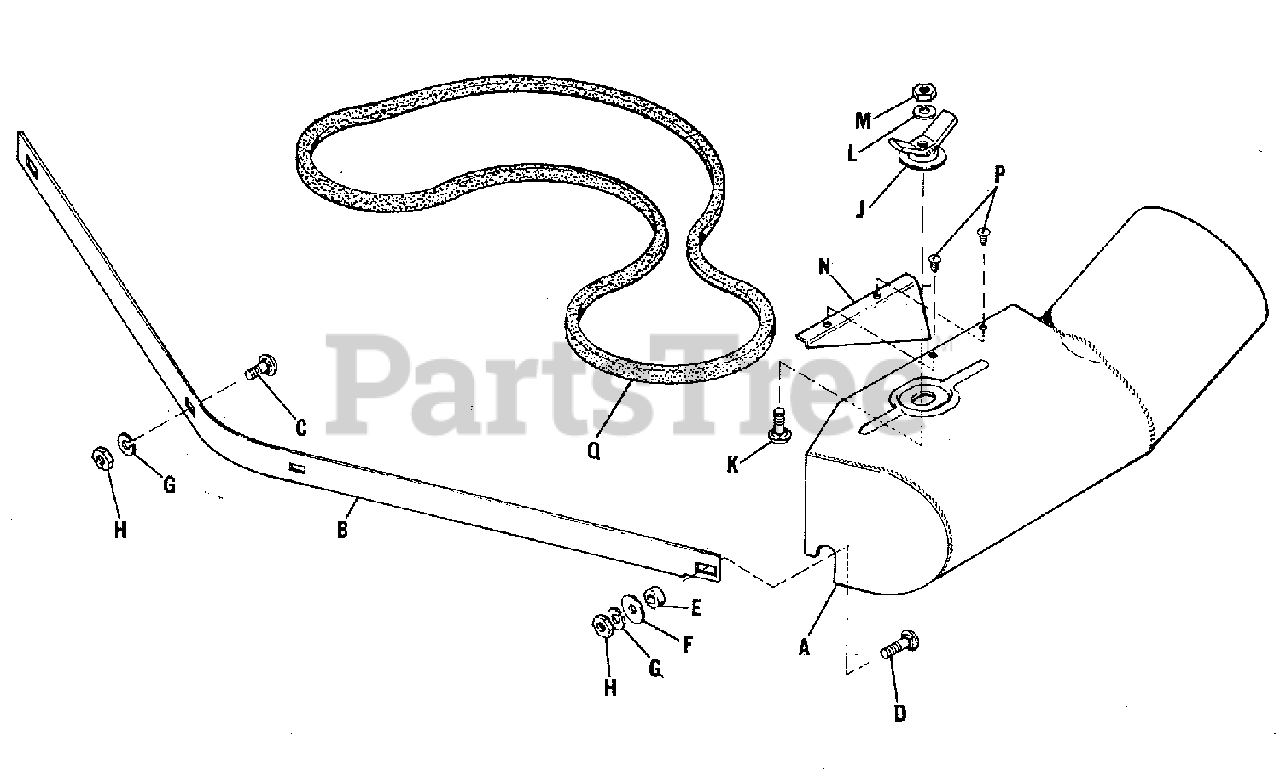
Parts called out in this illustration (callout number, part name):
A	HOUSING ASSEMBLY, Collector Side
B	BALFFE, Front
C	BOLT, Carriage, 3/8"-16 x 1" Lg.
D	BOLT, Carriage, 3/8"-16 X 1-1/4" Lg.
G	WASHER, Lock, 3/8"
H	NUT, Hex, Full, 3/8"-16
J	NUT ASSEMBLY
K	CARRIAGE BOLT, 3/8"-16 x 1" Lg.
L	WASHER, Lock, 3/8"
M	NUT, Hex, Full, 3/8"-16
N	BAFFLE, Mower
P	SCREW, Self Tapping, #10-24 x 1/2" Lg.
Q	BELT, "V"
